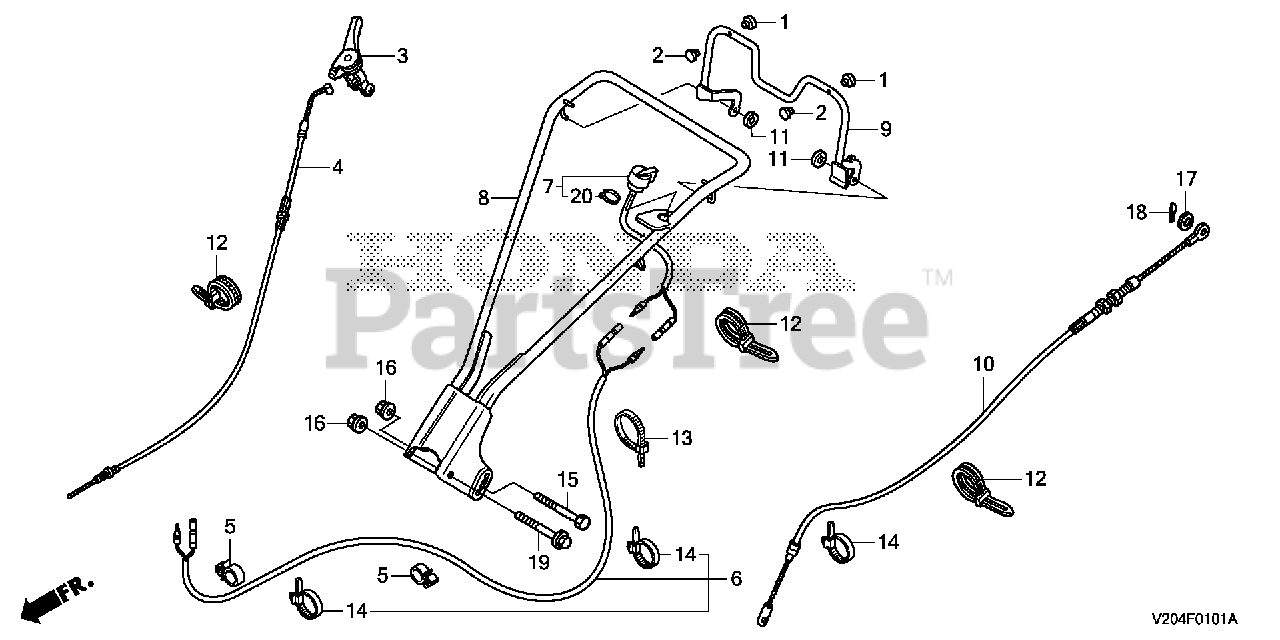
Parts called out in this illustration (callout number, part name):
3	LEVER ASSY., THROTTLE (COO)
4	CABLE, THROTTLE
5	CLIP, HARNESS
6	WIRE, ENGINE STOP SWITCH
7	SWITCH ASSY., ENGINE STOP
8	PIPE, HANDLE *NH105* (COO) (MAT BLACK)
9	LEVER, CLUTCH *NH105* (COO) (MAT BLACK)
10	CABLE, CLUTCH
11	WASHER, SPECIAL (8MM)
12	BAND, WIRE HARNESS
13	BAND, HARNESS (BLACK)
14	CLIP, HARNESS BAND (145MM) (BLACK)
15	BOLT, HEX. (10X150)
16	NUT, FLANGE (10MM)
17	WASHER, PLAIN (6MM)
18	PIN, SPLIT (2.0)
19	BOLT, FLANGE (10X150)
